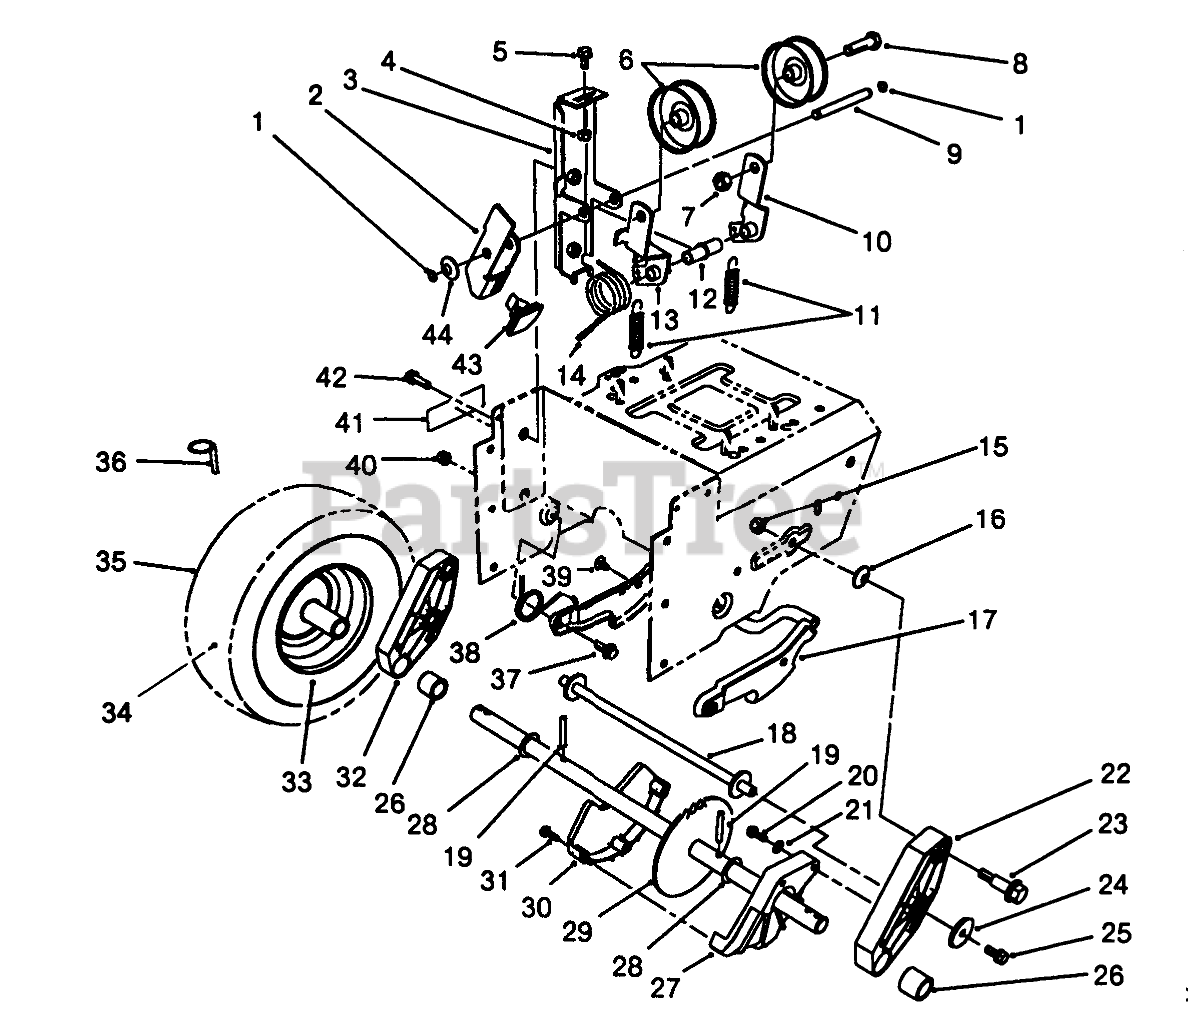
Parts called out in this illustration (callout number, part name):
1	RING-RETAINING
2	ARM-BRAKE
3	IDLER ARM BRACKET ASM
4	NUT-LOCK, NI
5	SCREW-HHF
6	PULLEY-IDLER
7	NUT-LOCK, NI
8	SCREW-HH
9	PIN-IDLER
10	ARM-IDLER, TRACTION
11	SPRING-EXTENSION
12	BUSHING-IDLER
13	ARM-IDLER, IMPELLER
14	SPRING-TORSION
15	NUT-LOCK, NI
16	WASHER-SPRING
17	Latch-Arm
18	PIVOT TUBE WA
19	PIN-ROLL, SLOTTED
20	Screw-Hex Flange Hd.
21	WASHER-FLAT
22	Pivot Arm Assembly L.H. (Incl. Ref. #26)
23	BOLT-SHOULDER
24	WASHER
25	SCREW-TAPTITE
26	BUSHING-AXLE
27	GUARD-CHAIN, LH
28	WASHER-THRUST
29	AXLE WA (24")
30	GUARD-CHAIN, RH
31	SCREW-PPH
32	Pivot Arm Assembly R.H. (Incl. Ref. #26)
33	Wheel
34	TUBE-INNER
36	PIN-LYNCH
37	SCREW-SHOULDER
38	SPRING-LATCH, TORSION
39	FASTENER-PANEL
40	NUT-LOCK, NI
41	Decal-Warning
42	SCREW-HHF
43	Brake Pad
44	WASHER-CURVED
